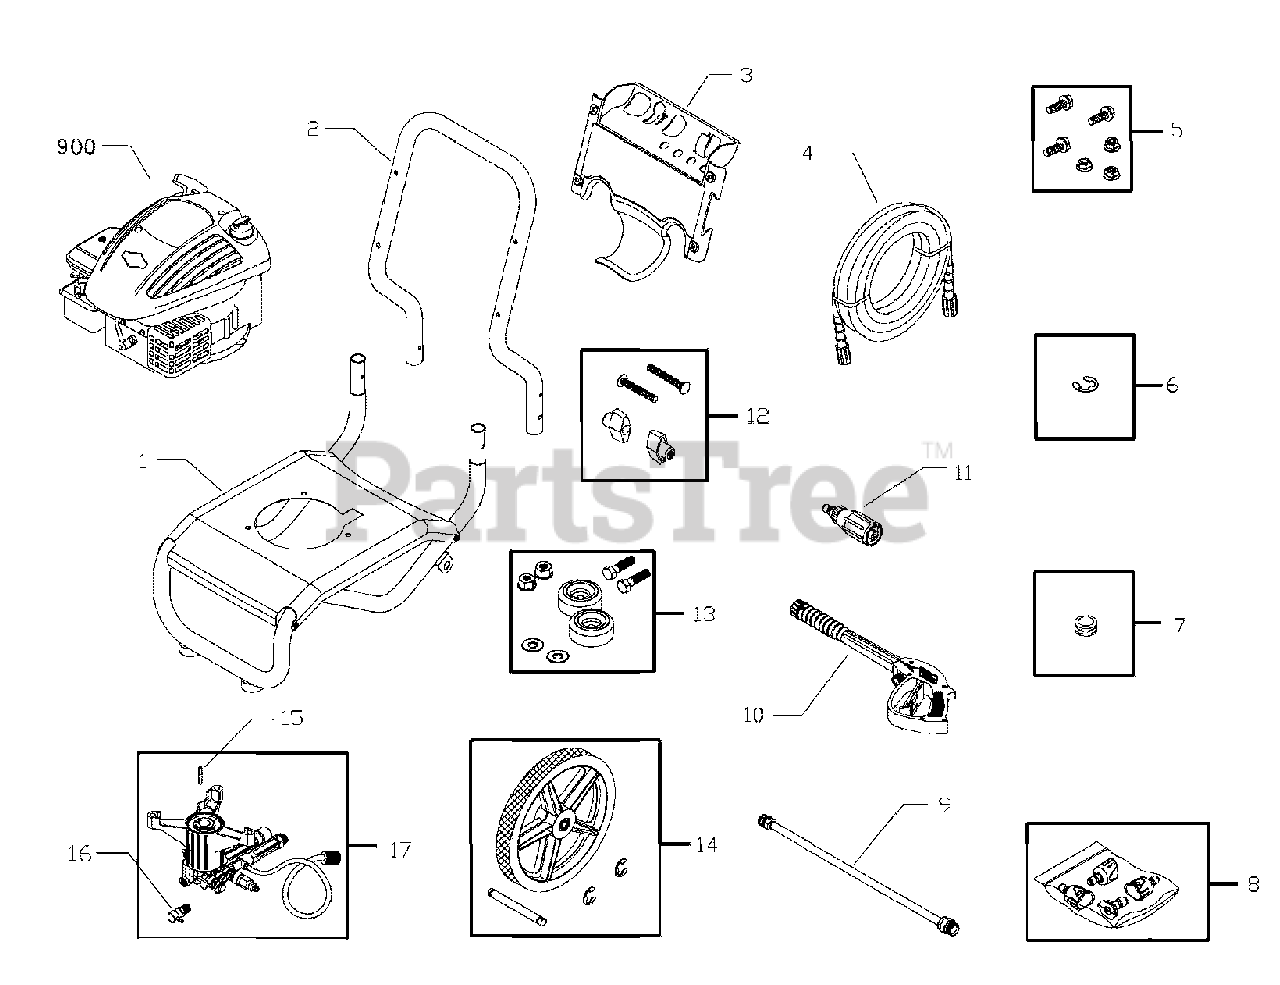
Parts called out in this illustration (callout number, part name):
3	KIT, Billboard with Clips
4	HOSE
5	KIT, Pump Mounting Hardware
6	KIT, E-Ring 1/2"
9	ASSY, Extension
10	GUN
12	KIT, Handle Connector
13	KIT, Vibration Mount
16	VALVE, Thermal Relief
17	PUMP
